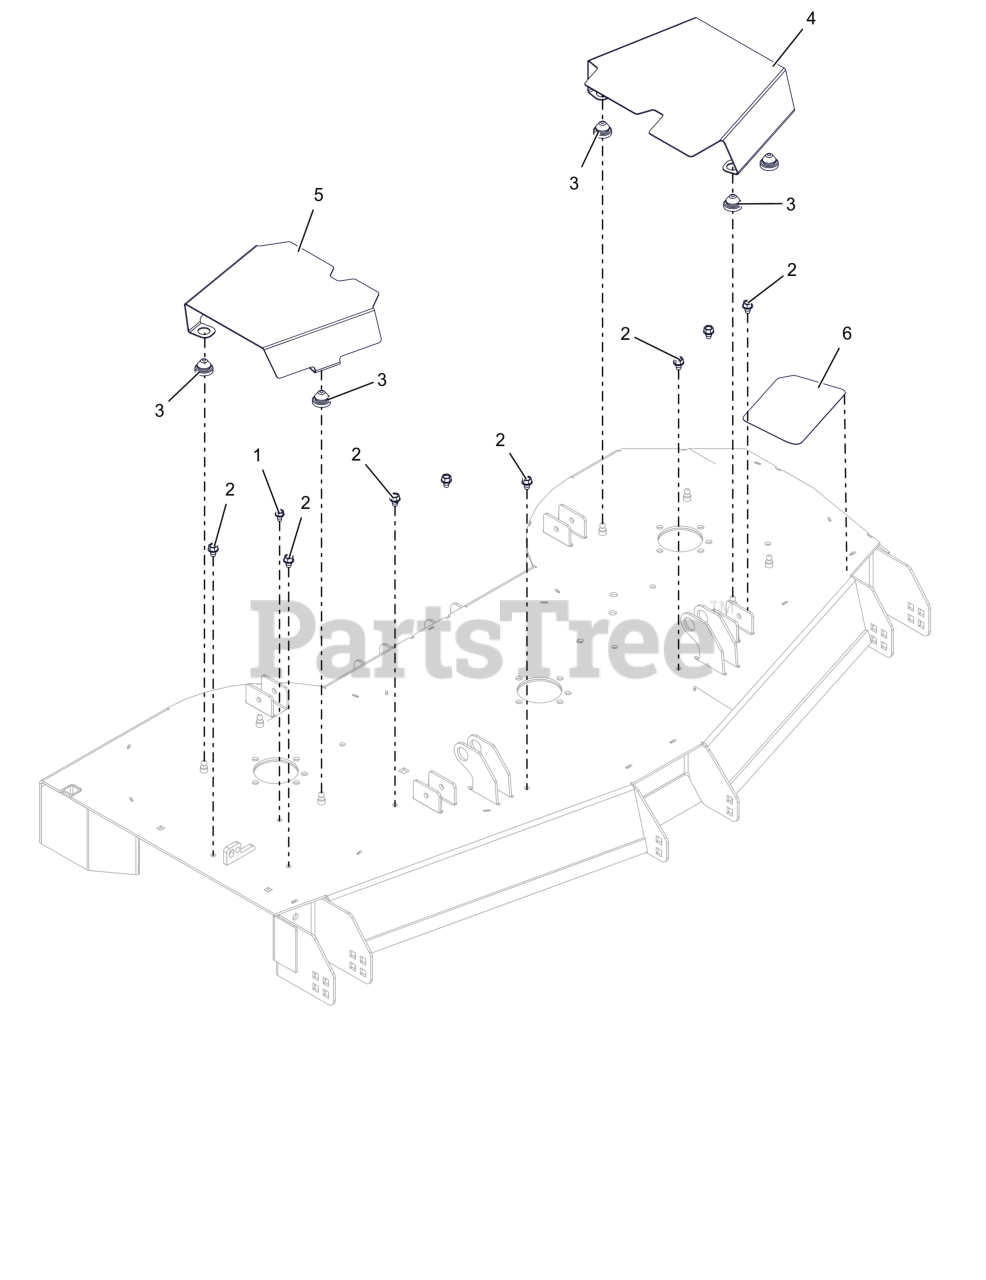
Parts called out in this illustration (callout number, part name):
1	SCR,TAP .312-18X.50 HWH TR ZCC
2	SCR,TAP .375-16X.50 HWH TR ZCC
3	COUPLING, RUBBER PUSH-IN
4	COVER- BELT 60" LEFT
5	COVER- BELT 60" RIGHT
6	GRIP, STEP ANTI SKID HD XF3
